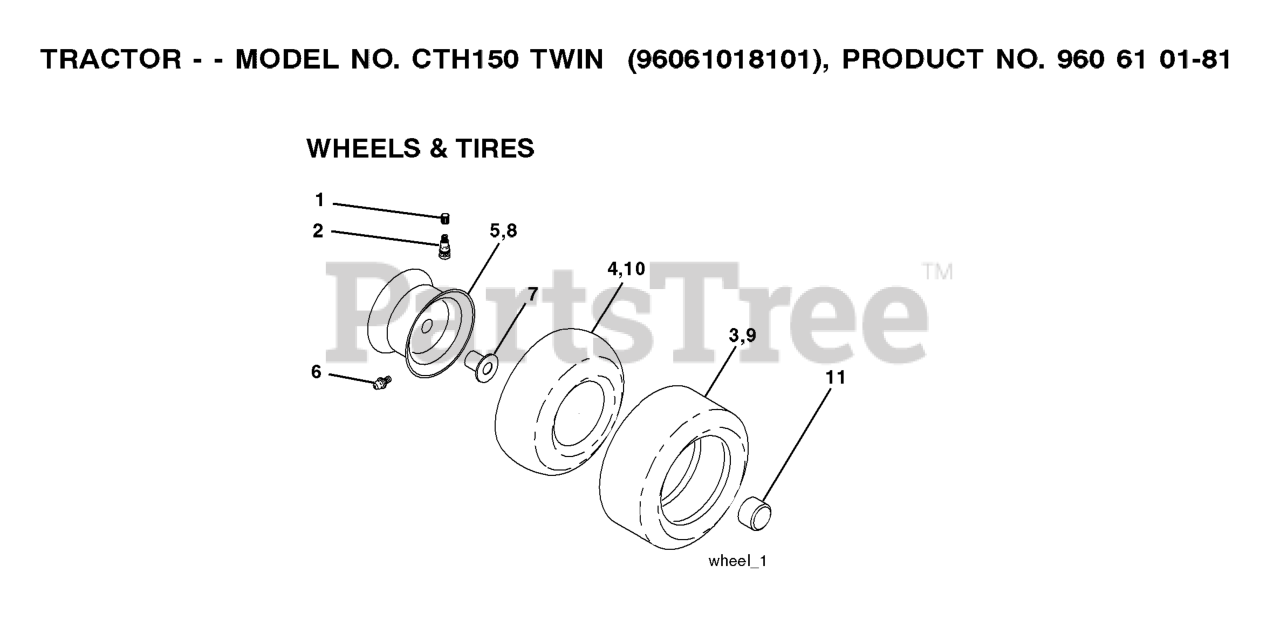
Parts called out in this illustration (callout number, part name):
2	VALVE STEM LT
3	TIRE HEAVY DUTY
4	TUBE.5.3/4.5/6
5	RIM ASM 6" FRONT SILVER
6	FITTING LT
7	BEARING T
8	RIM ASM 8" REAR SILVER
9	TIRE.TS.20X10-8
10	TUBE
11	CAP, AXLE BLK
